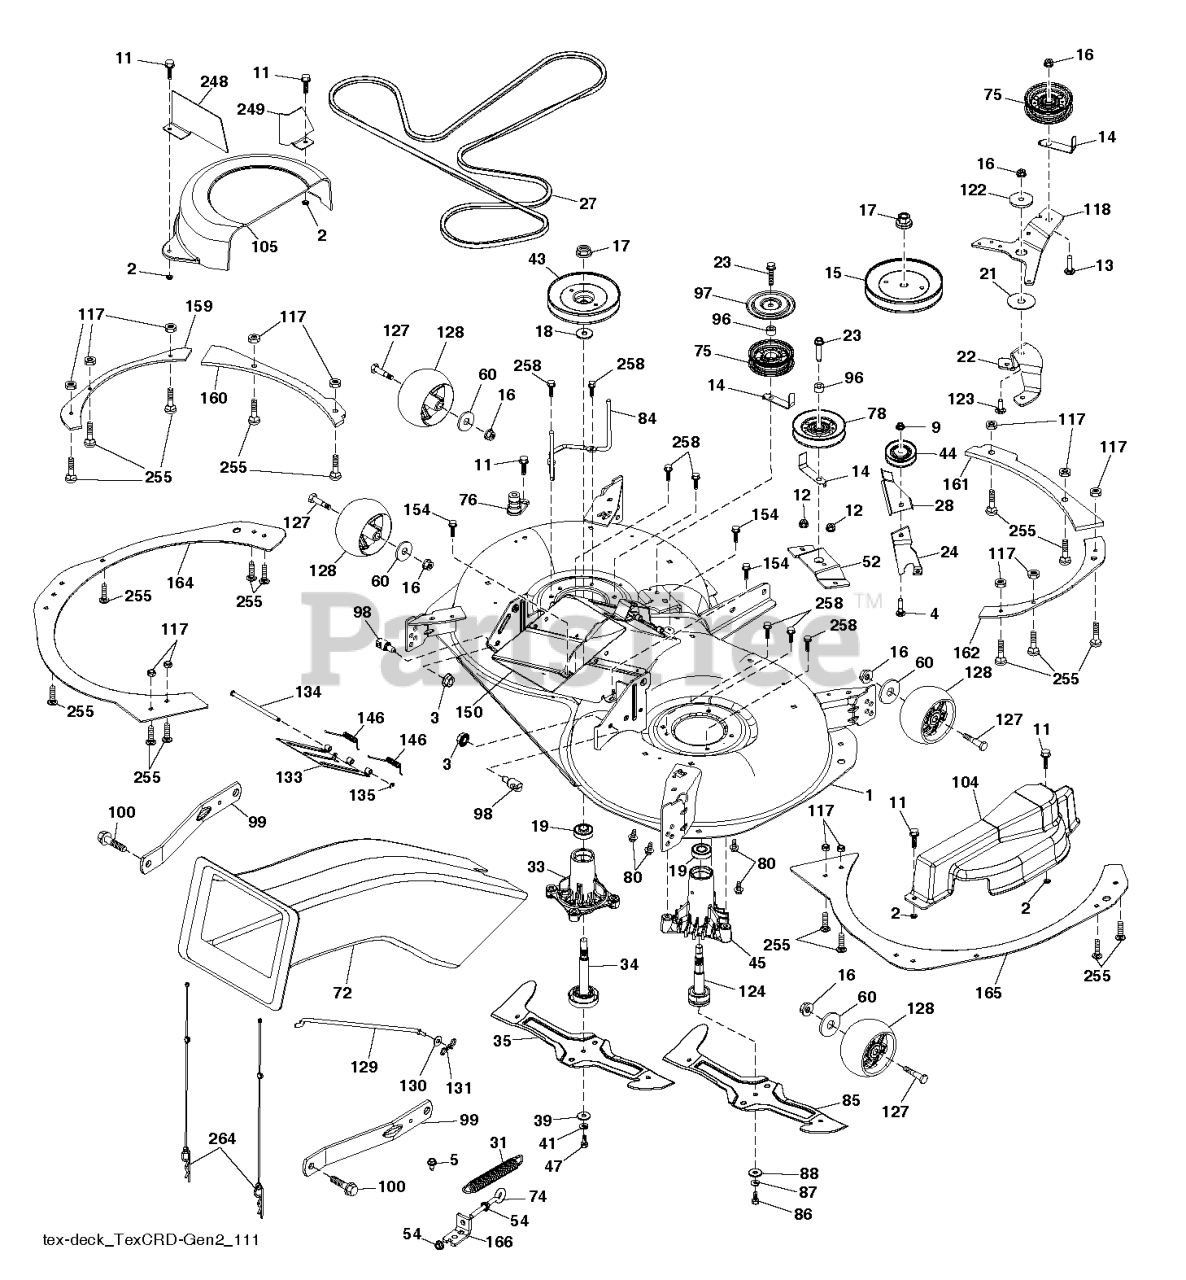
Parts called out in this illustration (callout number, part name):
1	KIT.SVC.DECK.WELD.107HP.EL.498
2	PALNUT 1/4
3	NUT LOCK HEX FLANGE 5/16-18
4	BOLT.CARRIAGE.5/16-18
5	BOLT.5/16HEX.WHS.HD
9	NUT HEX FLG NYLOCK BLK 5_16-1
11	SCREW.1/4-20X5/8
12	5/16-18 NYLOC FLANGE NUT
13	BOLT.3/8-16X1.50
14	KEEPER, BELT IDLER
15	PULLEY.MANDREL.5.438.P
16	NUT LOCK FLG 3/8-16 UNC
17	NUT.FLANGE.LOCK.TOP
18	WASHER.SPACER.MANDREL
19	BEARING.MANDREL.TOP.EXTENDED
22	BRACKET CRD IDLER ARM MOUNT BL
23	SCREW LT
24	BRACKET 107 CRD ANGLED V-IDLER
27	BELT 107 CRD DECK DRIVE BELT
28	KEEPER 107 CRD ANGLED IDLER KE
31	SPRING.EXTN.42.FCS.TR.DECK.DRV
33	RP.HOUSING.MANDREL.4PT.
34	SHAFT ASM.MNDRL.N/GREASEABLE
35	BLADE.3N1.LH.CRD
39	WASHER.7/16.FLAT
41	WASHER 7/16 LOCK
43	PULLEY PULLEY MANDREL 5.438 PD
44	PULLEY.V-IDLER.
45	HOUSING.MANDREL.VENTED (MACHD)
47	SCREW.SEMS.7/16-20X1.HEX.HEAD
52	BRACKET 107 CRD CENTER V-IDLER
54	NUT 5/16C WHIZ
60	WASHER.5/16.FLAT.STE.STD.
72	CHUTE.SLOTTED.HOLES.TEX.CRD.II
74	EYE BOLT 5/16 X 3.50
75	FLAT IDLER PULLEY
76	PORT.WASHOUT
78	REPL BY 532 1467-63
80	BOLT 5/16C X 3/4" CARRIAGE
84	KEEPER KEEPER. LH MANDREL BELT
85	BLADE.3N1.RH.CRD
86	BOLT.3/8-24X1.25GR8. LHTHRD
87	SLW 3/8 STD
88	WASHER.BLADE
96	SPACER
97	PROTECTOR
98	STUD.FASTNER.W/ANTI-ROTATE
99	ARM.SUSPENSION.MOWER.R
100	BOLT.SHOULDER
104	COVER.MANDREL.107.RH.GEN.2
105	COVER.MANDREL.107.LH.GEN.2
117	NUT T
118	ARM ARM. CLUTCHING 107 TEX CRD
122	SPACER.RETAINER.MOWER
123	BOLT
124	MANDREL SHAFT NON/GREASE
127	BOLT.SHOULDER.3/8-16X3-5/8.
128	WHEEL.GAUGE.RALLY
129	ROD ROD. SWAY CRD GEN II
130	WASHER
131	PIN.COTTER.5/16.BOW TI
133	COVER DOOR.107 CM CRD EZ MULCH
134	PIN PIN.HINGE
135	E-RING.5/16"
146	SPRING SPRING: EZ MULCH DOOR
150	CHUTE.107TCRD.X-MULCH.CHT.EDIP
154	SCREW T-30 1/4-20 X
159	REINFORCE.PLATE.LH.FT.X431
160	REINFORCE.PLATE.LHS.BOLT.431
161	REINFORCE.PLATE.RH.FRT.X431
162	REINFORCE.PLAT.RH.SD.BLT.X431
164	BAFFLE.PLATE.PNT.107CRD.LT.BLK
165	BAFFLE.PNT.107.CRD.PLATE.RT.BK
166	BRACKET CRD ELEC DECK DRIVE TE
248	GUARD BELT.CRD.LH.REAR.ISO X43
249	GUARD BELT.CRD.LH.FRNT.ISO X43
255	RHSNB, 1/4-20 X 1, GR5
258	BOLT.HEX.WASHR.HED.313-18X1.19
264	RETAINER.ASM.UPPERCHUTE.CRD2.5
